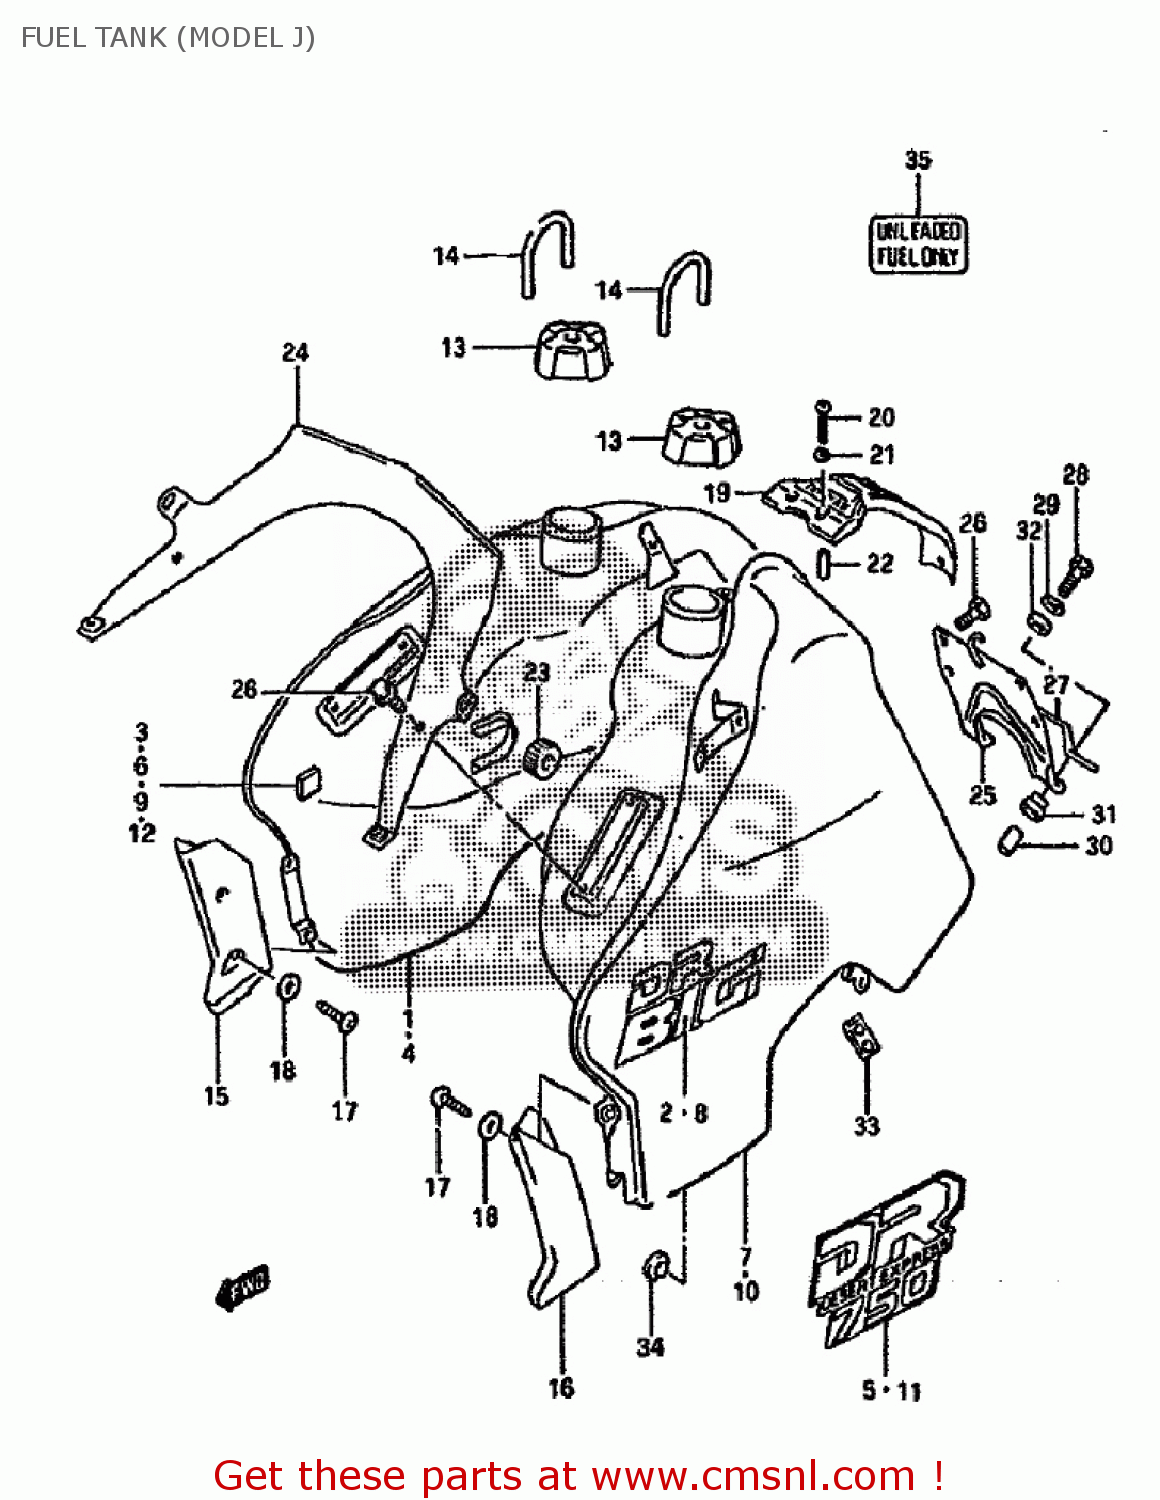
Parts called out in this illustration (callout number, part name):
1	TANK ASSY,FUEL RH (WHITE)
2	EMBLEM,FUEL TANK
3	CUSHION
4	TANK ASSY,FUEL RH (WHITE)
5	EMBLEM
6	CUSHION
7	TANK ASSY,FUEL LH (WHITE)
8	EMBLEM,FUEL TANK
9	CUSHION
10	TANK ASSY,FUEL LH (WHITE)
11	EMBLEM
12	CUSHION
13	CAP ASSY,FUEL TANK
14	HOSE
15	COVER,FUEL TAN
16	COVER,FUEL TANK FR,L
17	SCREW 6X12
18	WASHER
19	COVER,FUEL TANK CENTER (BLACK)
20	SCREW (6X40)
21	WASHER
22	SPACER
23	CUSHION
24	BRACKET,FRONT
25	BRACKET,REAR
26	BOLT
27	BRACKET,SEAT FRONT HOOK
28	BOLT
29	WASHER (6.5X24X1.6)
30	SPACER
31	CUSHION
32	CUSHION
33	CUSHION
34	CUSHION
35	LABEL,FUEL CAUTION
